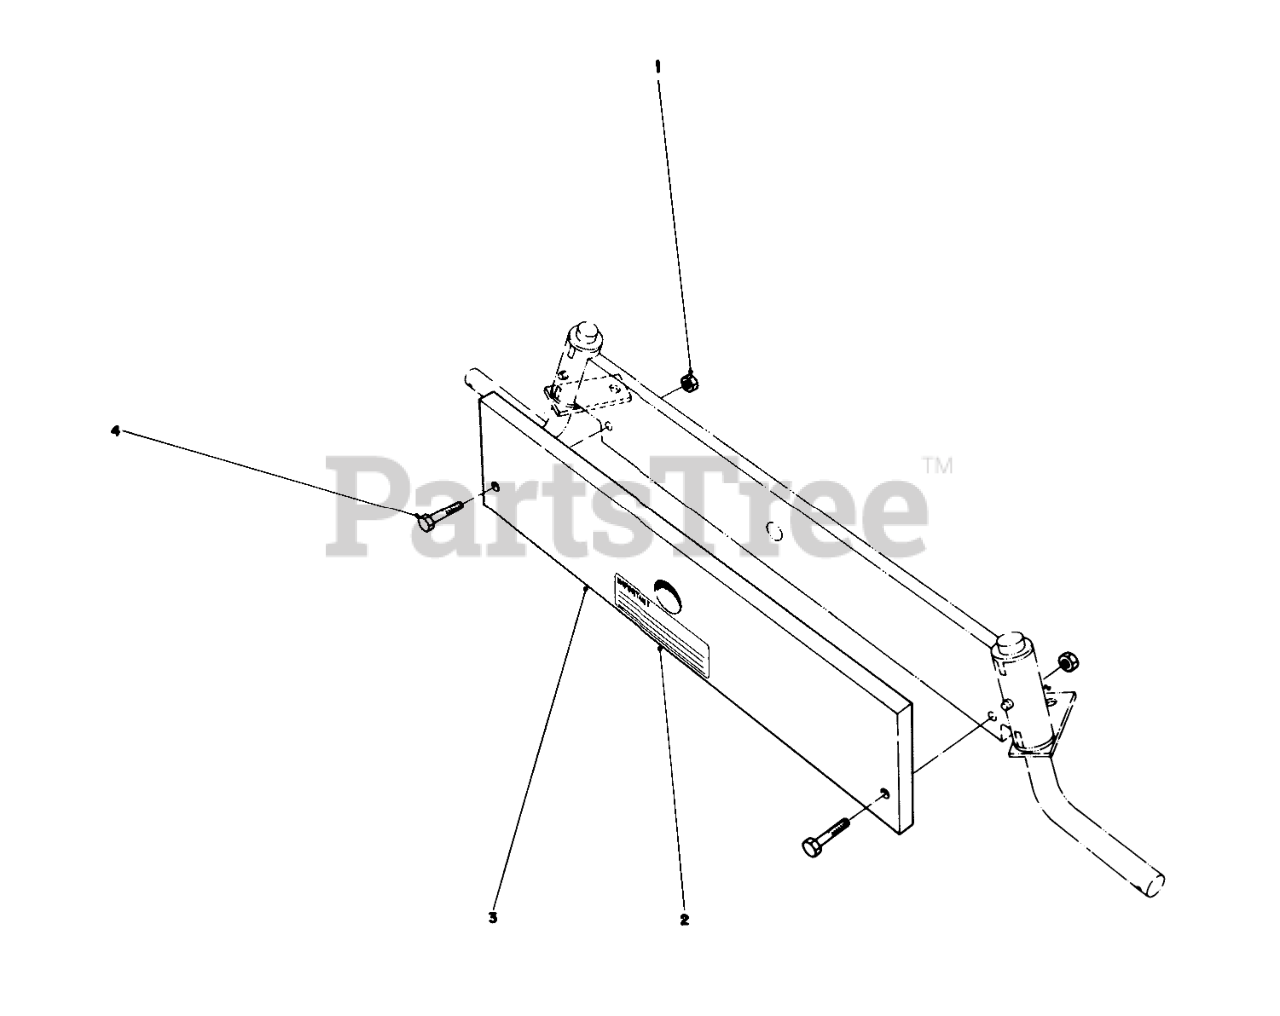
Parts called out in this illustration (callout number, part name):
2	Decal-Warning
3	COUNTERWEIGHT B
4	SCREW-HH
